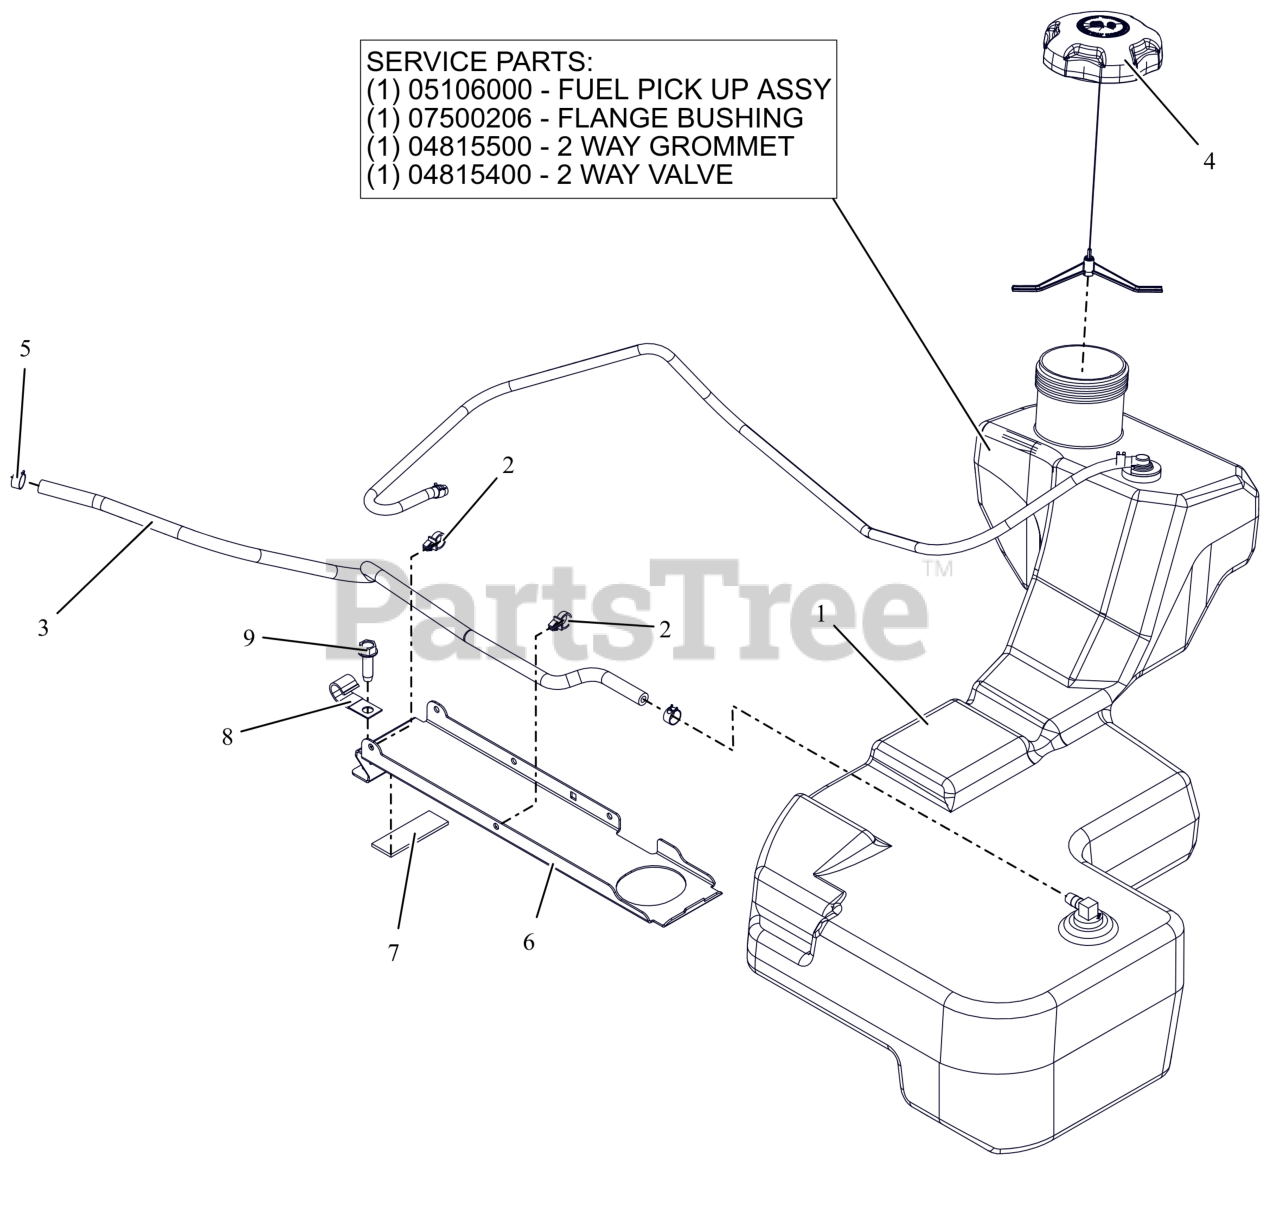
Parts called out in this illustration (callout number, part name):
1	ASM, FUEL TANK-HD
1	ASM, HD FUEL PICK-UP
1	BSHG-FLG .375X1.062X.625 NITR
1	GROMMET, 2-WAY
1	VALVE, 2-WAY
2	ROUTING CLIP (1/2" ID)
3	1 INCH OF HOSE, .25 LOW-PERM BULK GAS
4	CAP, FUEL - 3.50 RATCHET INLET VENT
5	CLAMP, FUEL LINE
6	BRKT, FUEL TANK HOLD DOWN
7	PAD,RBR 1.0"X3.0" W/ADHESIVE
9	SCR,TAP .375-16X1.25HWH TR ZCC
